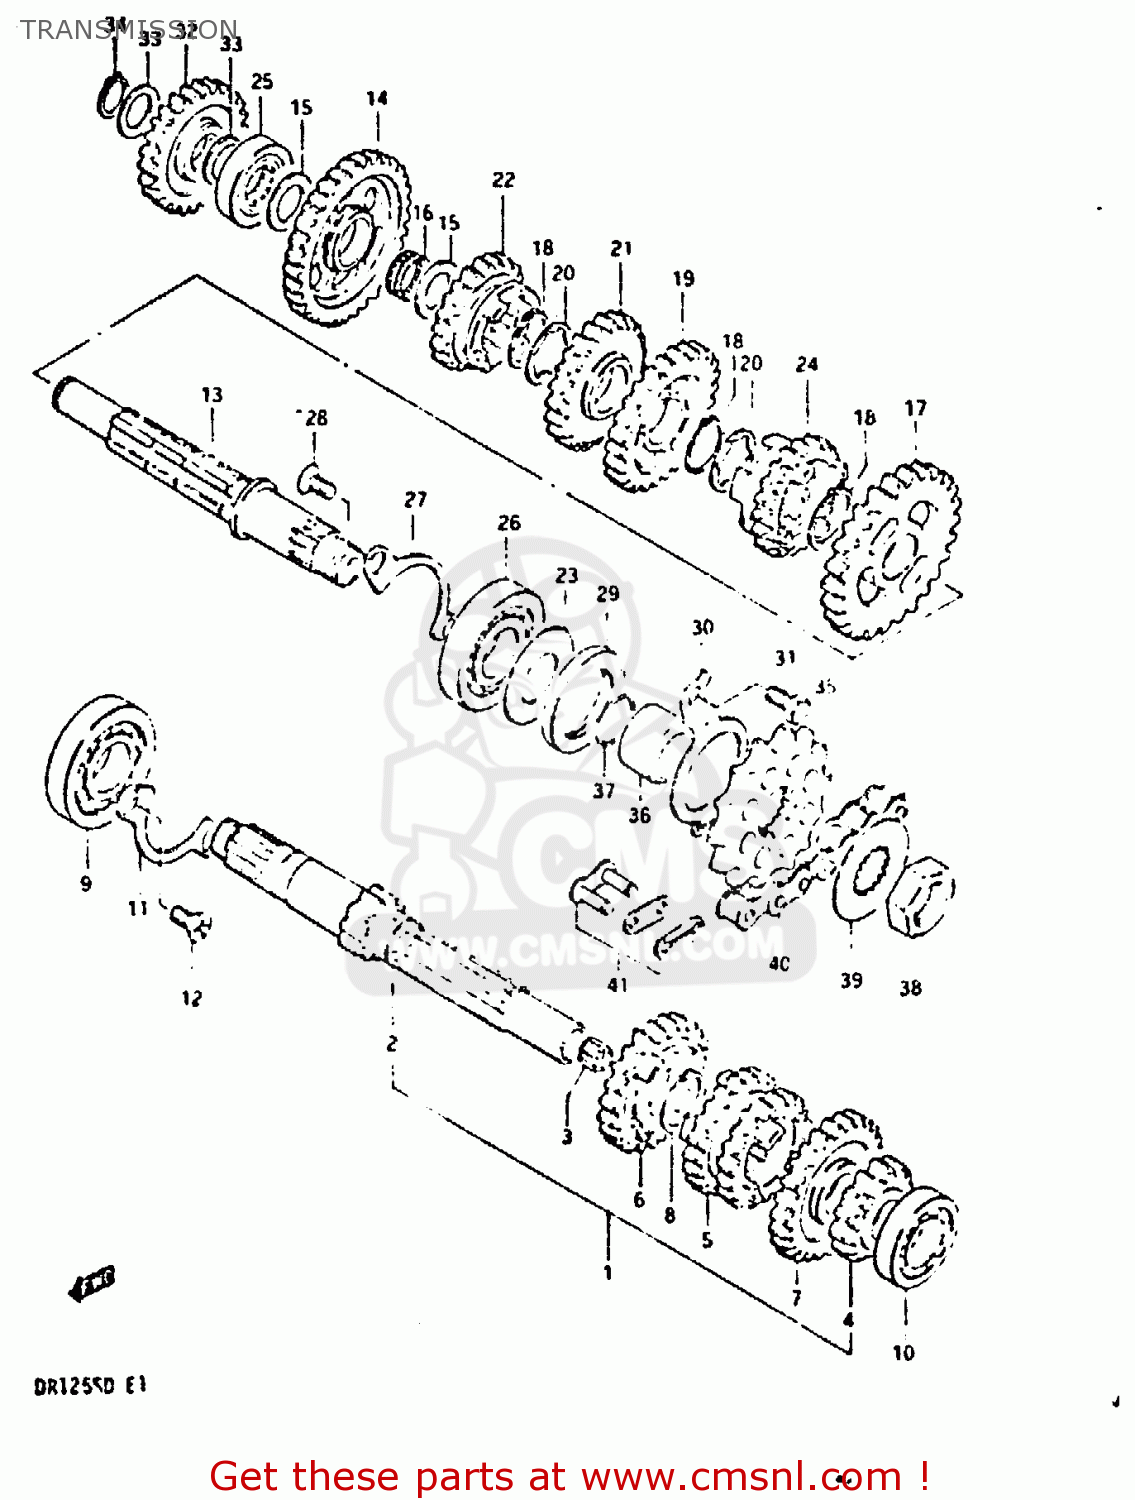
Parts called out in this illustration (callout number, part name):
1	SHAFT,COUNTER
2	SHAFT,COUNTER
3	BUSHING
4	GEAR,SECOND DRIVE
5	GEAR,THIRD & FOURTH DRIVE,N
6	GEAR,FIFTH DRIVE
7	GEAR,SIXTH DRIVE
8	CIRCLIP
9	BEARING
10	BEARING, LH
11	RETAINER,DRIVE SHAFT BEARING
12	SCREW
13	SHAFT,DRIVE
14	GEAR,FIRST DRIVEN
15	WASHER
16	BEARING(15X19X7.8)
17	GEAR,SECOND DRIVEN
18	CIRCLIP
19	GEAR,THIRD DRIVEN
20	WASHER,LOCK
21	GEAR,FOURTH DRIVEN
22	GEAR,FIFTH DRIVEN
23	WASHER,OIL SEALING
24	GEAR,SIXTH DRIVEN
25	BEARING(15X33X12)
26	Bearing
27	RETAINER,DRIVE SHAFT BEARING
28	SCREW
29	SEAL,OIL(27X40X6)
30	PLATE,DRIVESHAFT OIL
31	BOLT
32	GEAR,KICK STARTER IDLE
33	WASHER
34	CIRCLIP,15MM
35	SPROCKET,ENGINE
36	SPACER
37	O RING(D:2.4,ID:19)
38	NUT
39	WASHER,LOCK
40	CHAIN ASSEMBLY,DRIVE
41	JOINT SET,CHAIN
